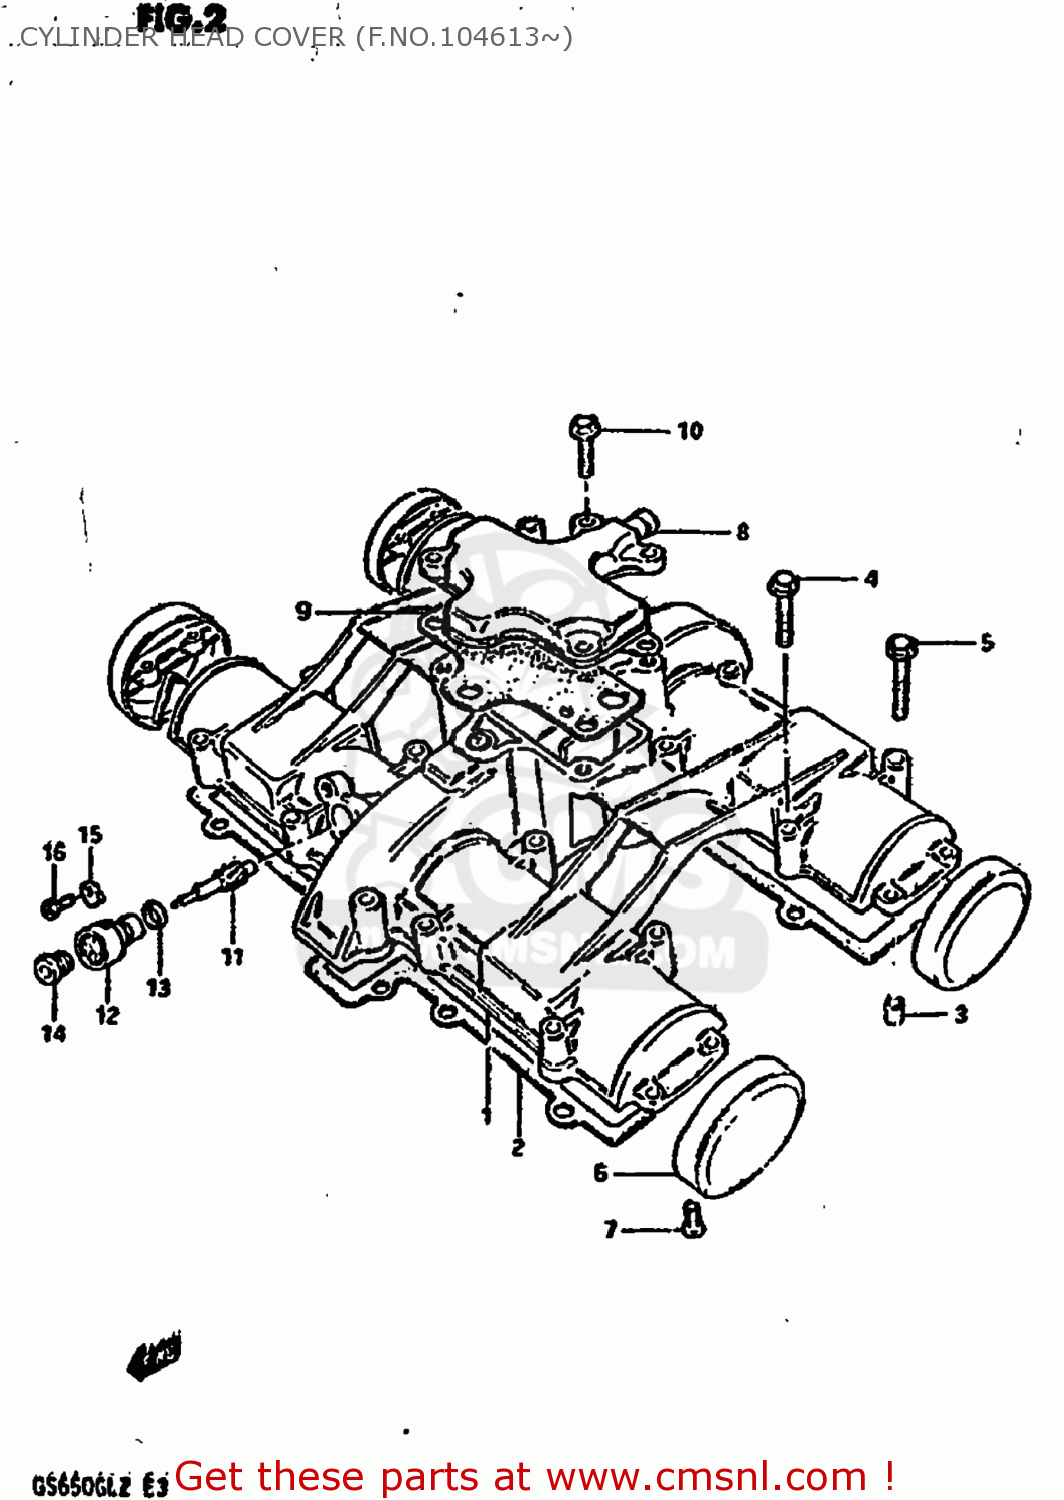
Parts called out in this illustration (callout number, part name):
1	COVER,CYLINDER HEAD
2	GASKET,CYLINDER HEAD COVER (MCA)
3	PIN(6.2X8X11)
4	BOLT
5	BOLT,UNDER
6	CAP,CYLINDER HEAD COVER
7	SCREW
8	COVER,BREATHER
9	GASKET (MCA)
10	BOLT,REAR
11	GEAR,TACHOMETER DRIVEN
12	SLEEVE,TACHOMETER DRIVE
13	SEAL,TACHOMETER DRIVEN
14	SEAL,OIL(5X12X8)
15	PLATE,TACH DRIVE GEAR SLEEVE
16	SCREW(5X12)
